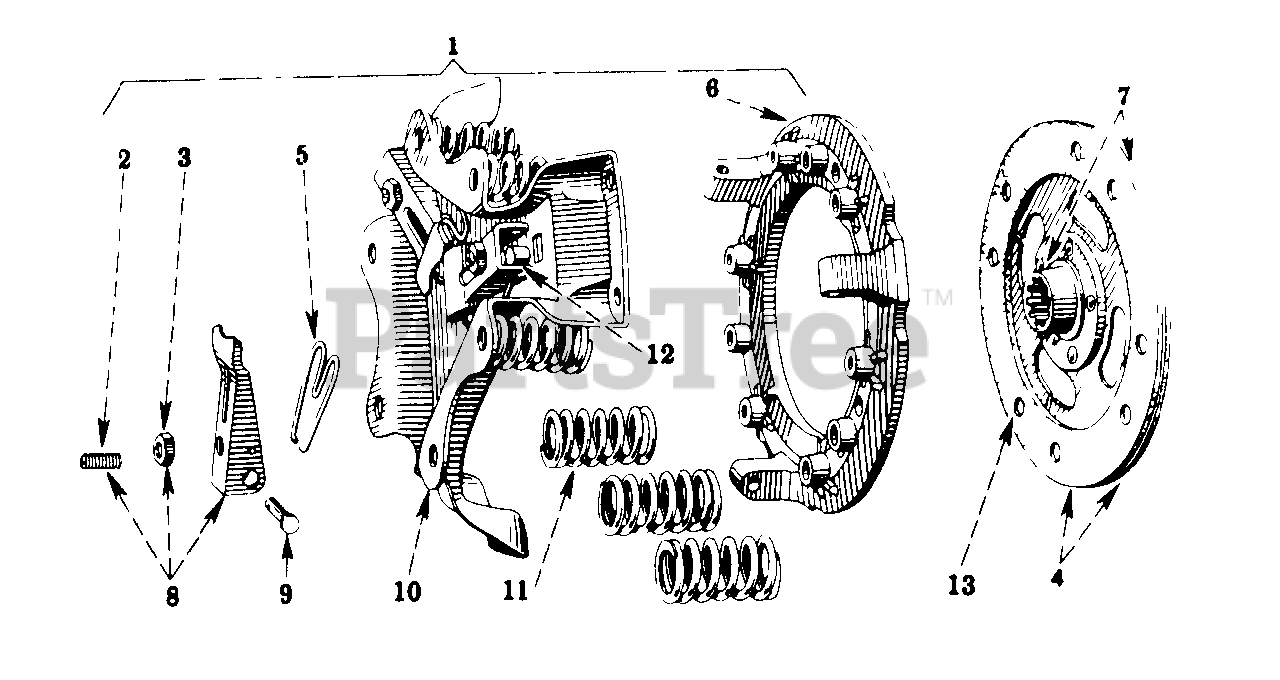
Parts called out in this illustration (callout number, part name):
1	PLATE ASSY, CLUTCH PRESSURE
2	SCREW, RELEASE LEVER ADJUSTING
3	NUT, ADJUSTING
4	FACING SET, CLUTCH
5	SPRING, RELEASE LEVER
6	PLATE, PRESSURE
7	DISC ASSY, CLUTCH DRIVEN
8	LEVER, RELEASE
9	PIN, RELEASE LEVER
10	PLATE, BACK
11	SPRING, PRESSURE
12	SEAT, ADJUSTING SCREW
13	RIVET, TUBULAR BRS
